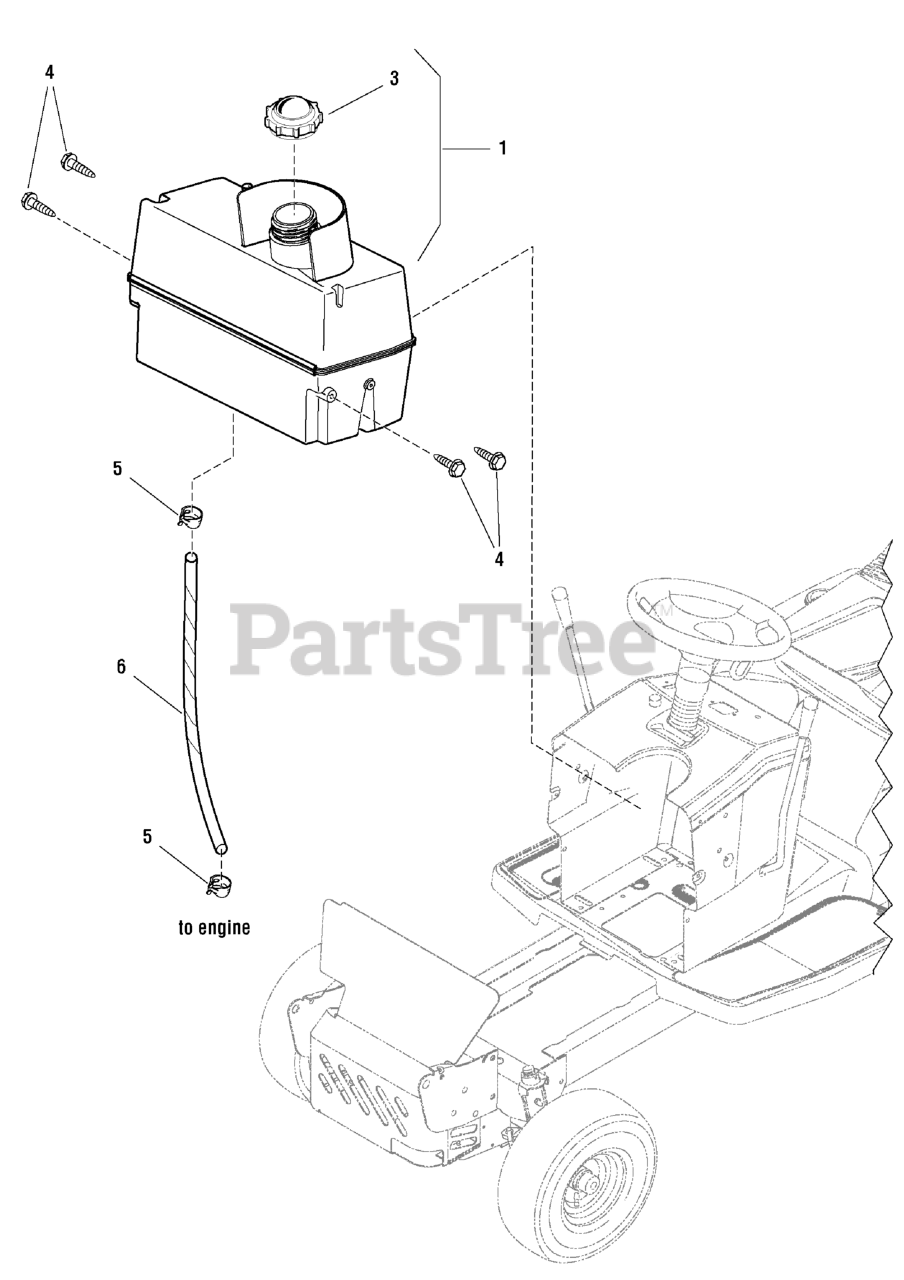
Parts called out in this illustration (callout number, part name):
1	FUEL TANK, With Cap, 5.3 litres (1.4 gallon)
1	FUEL TANK, With Cap, 10.6 litres (2.8 gallon)
3	CAP, Fuel Tank
4	SCREW, Thread Forming, 3/16-15 x 7/8
5	HOSE CLAMP
6	LINE, Fuel
